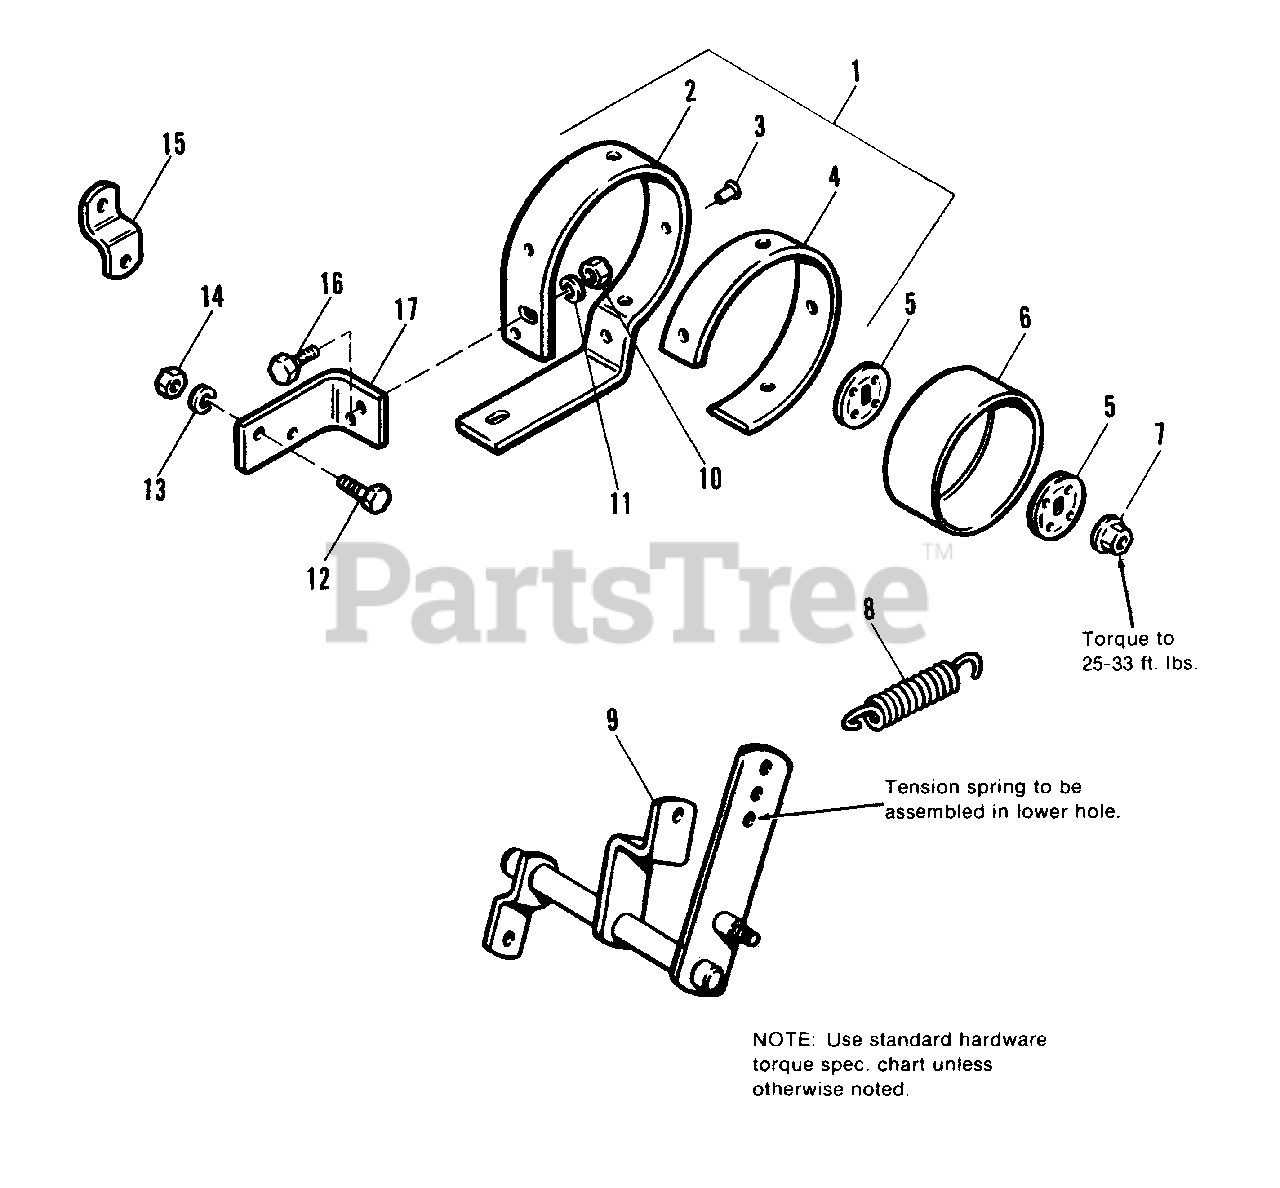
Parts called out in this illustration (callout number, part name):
1	BAND ASSY., Brake
2	BAND, Brake
3	RIVET, Tubular
4	LINING, Brake
5	WASHER, Special
6	DRUM, Brake
7	NUT, Hex, Flange, 7/16-14
9	LEVER ASSY., Pivot
10	NUT, Hex, Full, 1/4-20
11	LOCKWASHER, 1/4
12	CAPSCREW, Hex Hd., 3/8-16 x 1
13	LOCKWASHER, 3/8
14	NUT, Hex, Full, 3/8-16
15	CLIP, Spring
16	CAPSCREW, Hex Hd., 1/4-20 x 3/4
17	BRACKET, Brake Band
